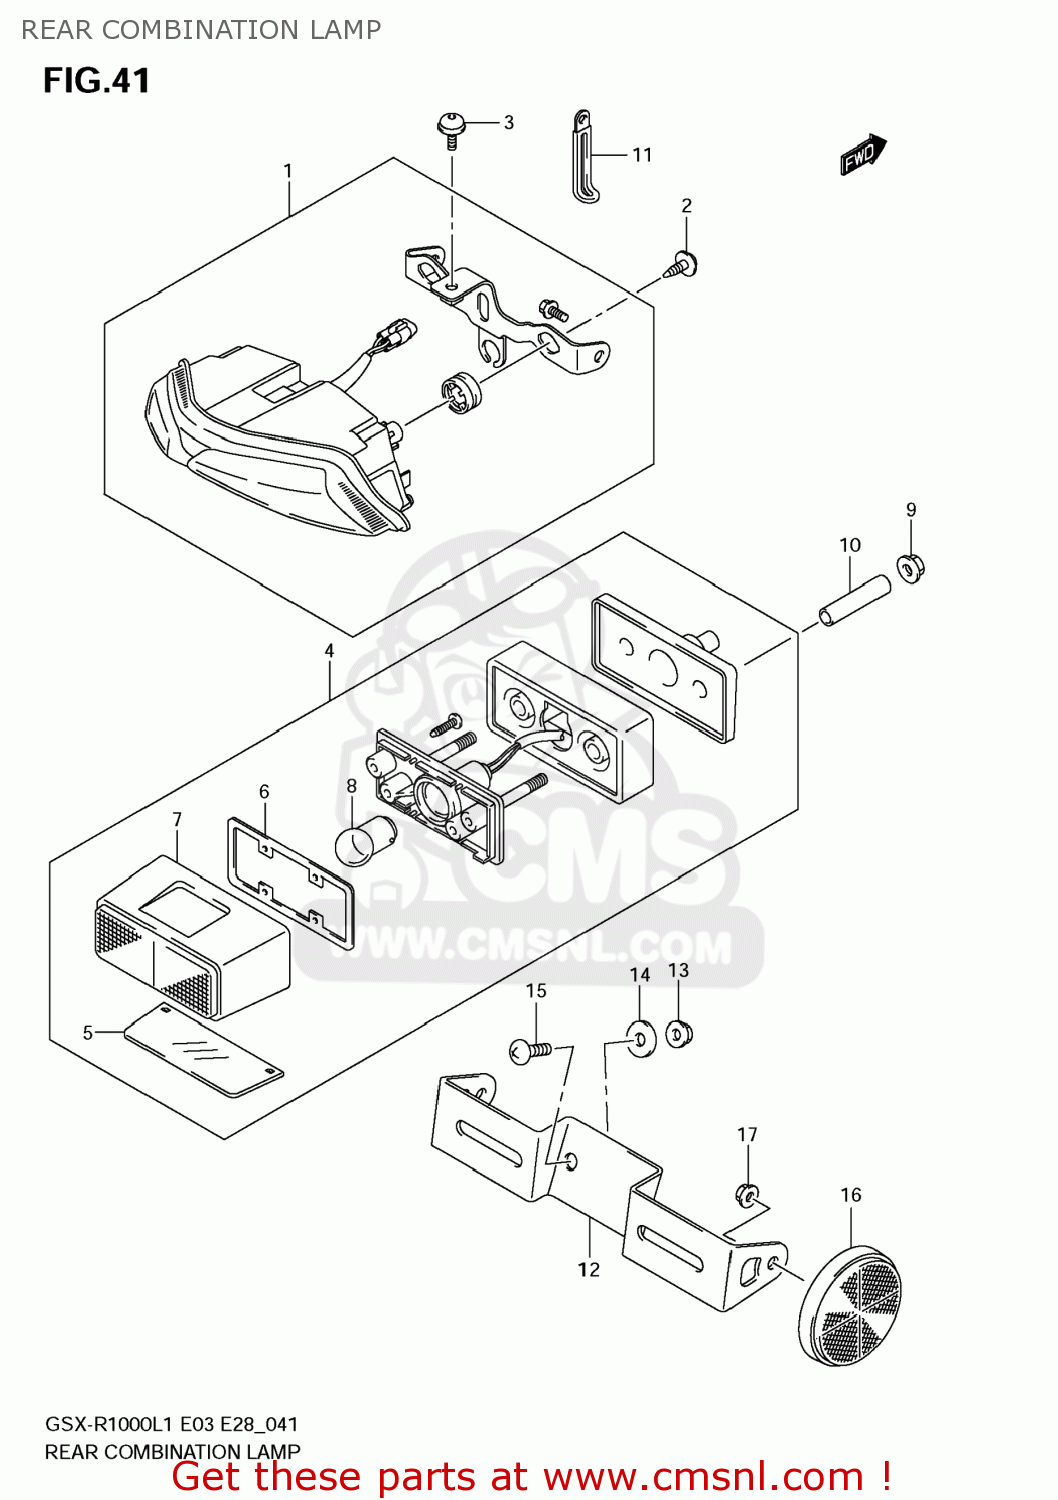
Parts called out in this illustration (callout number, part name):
1	LAMP ASSY,RR COMBINATION
2	BOLT(5X12)
3	SCREW(6X12)
4	LAMP ASSY,LICE
5	LENS LICENCE
6	GASKET (NAS)
7	COVER,LICENSE LAMP
8	BULB(12V5W,BF150-40160A)
9	NUT
10	SPACER(6.5X9X34)
11	CLAMP(L:45)
12	BRACKET,LICENSE PLATE
13	NUT
14	WASHER(6.5X20X1.2)
15	SCREW
16	REFLECTOR ASSY,RR SIDE
17	NUT
